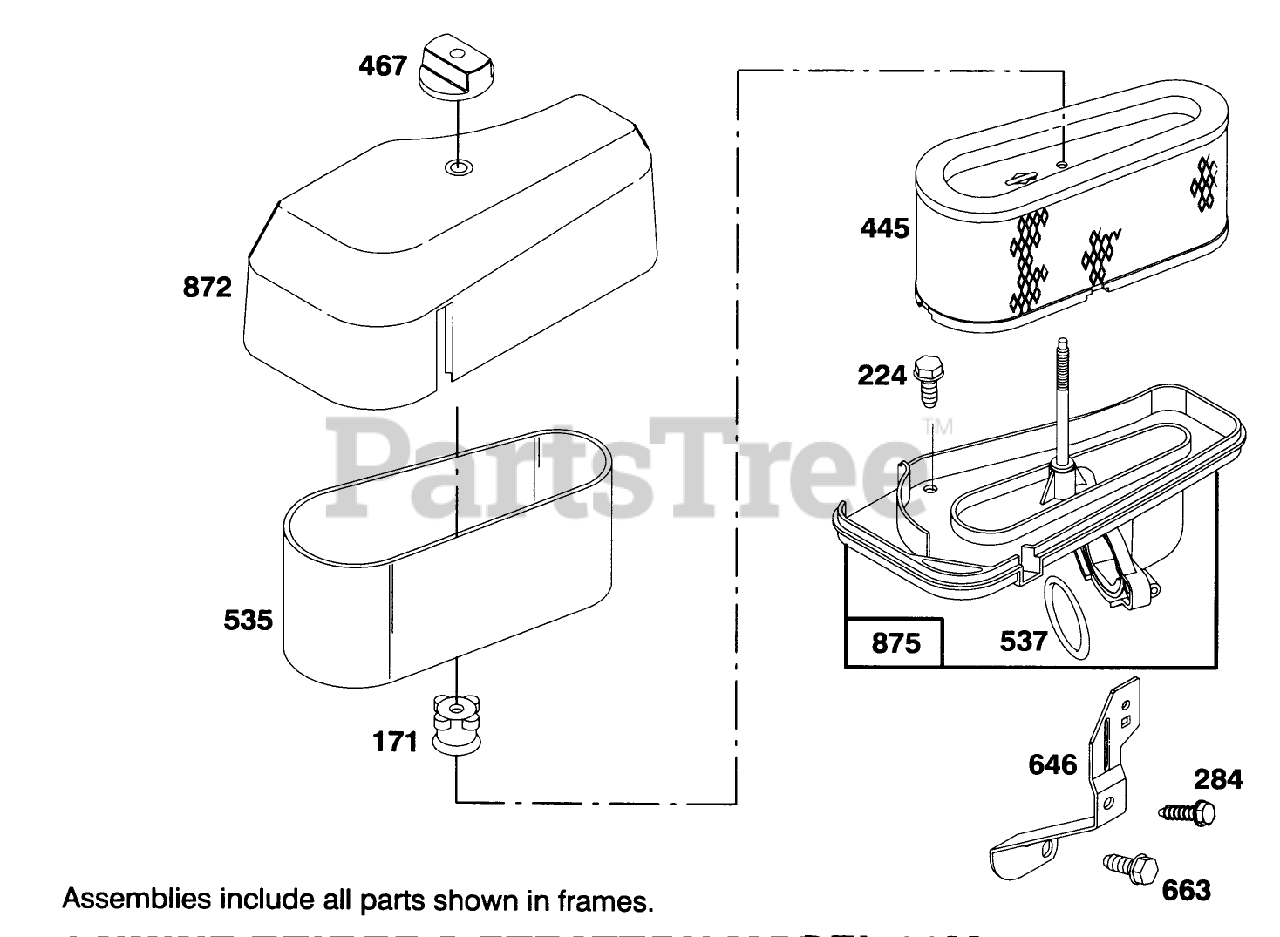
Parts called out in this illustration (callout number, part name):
224	Screw-Sem
284	Screw
445	Filter-Air
535	Filter-Air
537	O-Ring
646	Brace-Air Cleaner
663	Screw
872	Cover-Air Cleaner
875	Base-Air Cleaner
